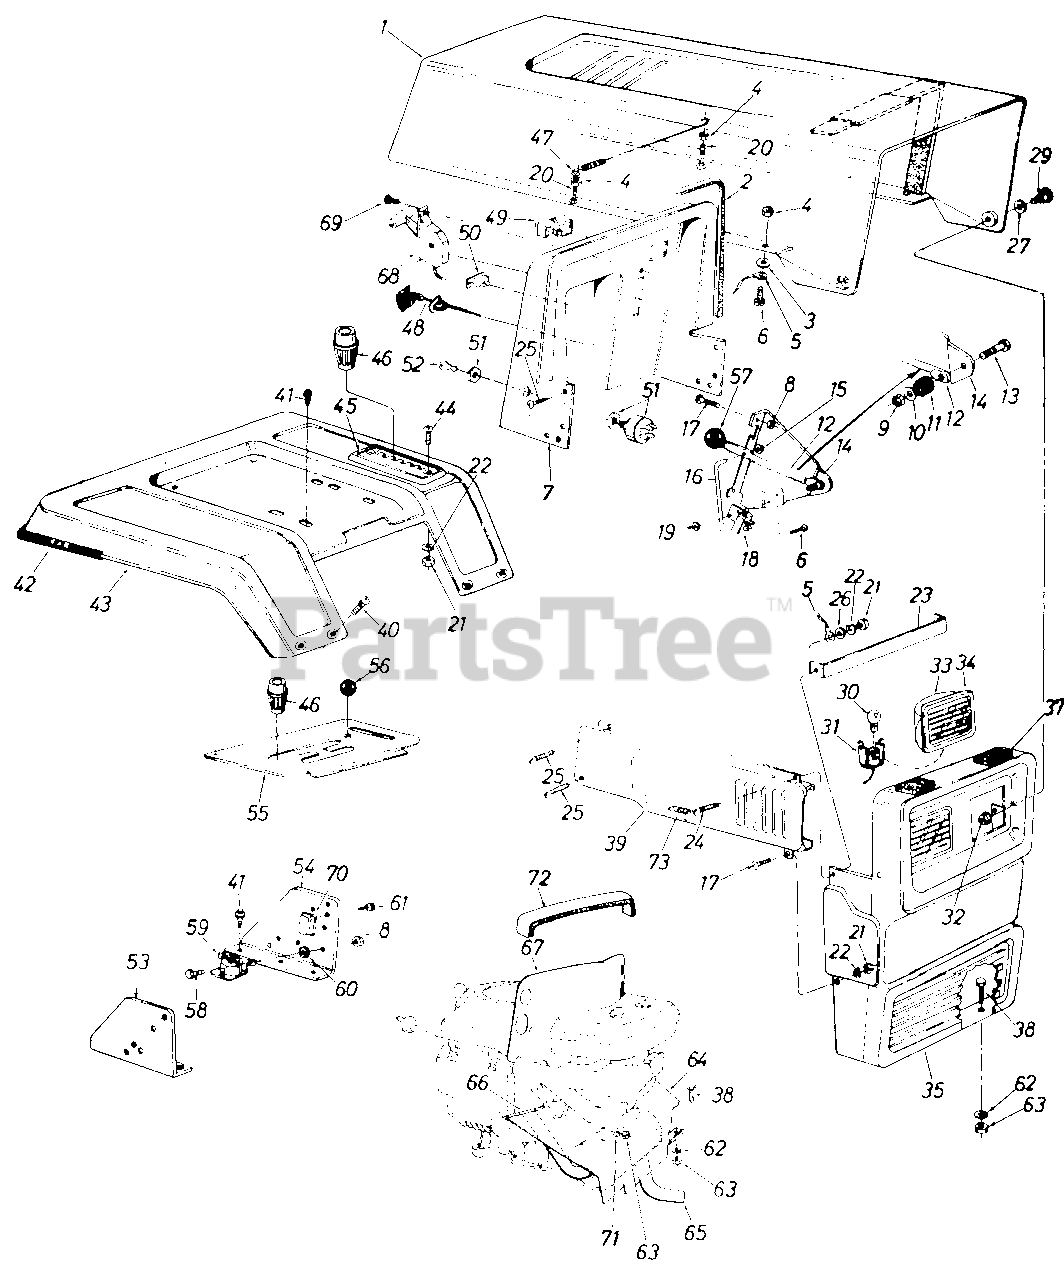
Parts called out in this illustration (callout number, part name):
3	Fl-Wash. .20" I.D. x .41" O.D.
4	Hex Sems Nut #10-24 Thd.
5	Hood Stop
6	Truss Mach. Scr. #10-24 x .5" Lg.
9	Hex L-Nut 1/4-20 Thd.
10	Fl-Wash. .281" I.D. x .73" O.D.
11	Rubber Washer
12	PTO Lever
13	Hex Bolt 1/4-20 x 1.25" Lg.
14	Deck Clutch Control Brkt.
15	Push Cap
16	Deck Control Rod
17	Truss Mach. Scr. 1/4-20 x .5" Lg.
18	Safety Switch
19	Hex Nut #10-24 Thd.
20	Hex Bolt 10-24 x 1.0" Lg.
21	Hex Nut 1/4-20 Thd.
22	L-Wash. 1/4" I.D.
23	Tie Strap Grille
24	Truss Mach. Scr. 1/4-20 x .75"Lg.
25	Hex TT-Tap Scr. 1/4-20 x .75" Lg.
26	Fl-Wash. .25" I.D. x.62"
27	Spr. Wash. .39" I.D. x .62"
29	Shld. Bolt .375" Dia. x .125" Lg.
30	Lamp
31	Socket
32	Locking Flange Nut 1/4-28 Thd.
33	Headlight Housing
34	Headlight Lens
38	Hex Bolt 5/16-18 x .75" Lg.
41	Hex Wash. AB-Tap Scr. 5/16 x .75" Lg.
42	Trim Strip 81" Lg.
43	Fender
44	Truss Mach. Scr. 1/4-20 x .62" Lg.
45	7-Speed Selector Plate
46	Shift Knob
47	Hood Spring
48	Choke Control 46" Lg.
49	Ammeter
50	Light Switch
51	Ignition Switch
52	Ignition Key
53	Dash Support Brkt. R.H.
54	Dash Support Brkt. L.H.
55	Transmission Cover
56	Ball Knob
57	Knob Blade Glutch
58	Hex Bolt 1/4-20 x .5" Lg.
59	Solenoid
60	Ext. L-Wash. 1/4" I.D.
61	Hex Wash. Hd. Scr. 1/4 x .5" Lg.
62	L-Wash. 5/16" I.D.
63	Hex Nut 5/16-18 Thd.
64	Front Heat Shield
65	Muffler
66	Trim Strip 10" Lg.
67	Top Shield
68	Throttle Control Box Ass'y.
69	Truss Mach. AB-Tap Scr. #10 x .5" Lg.
70	Circuit Breaker
71	Spec. L-Wash. 5/16" I.D.
72	PVC Foam
73	Rubber Strip
